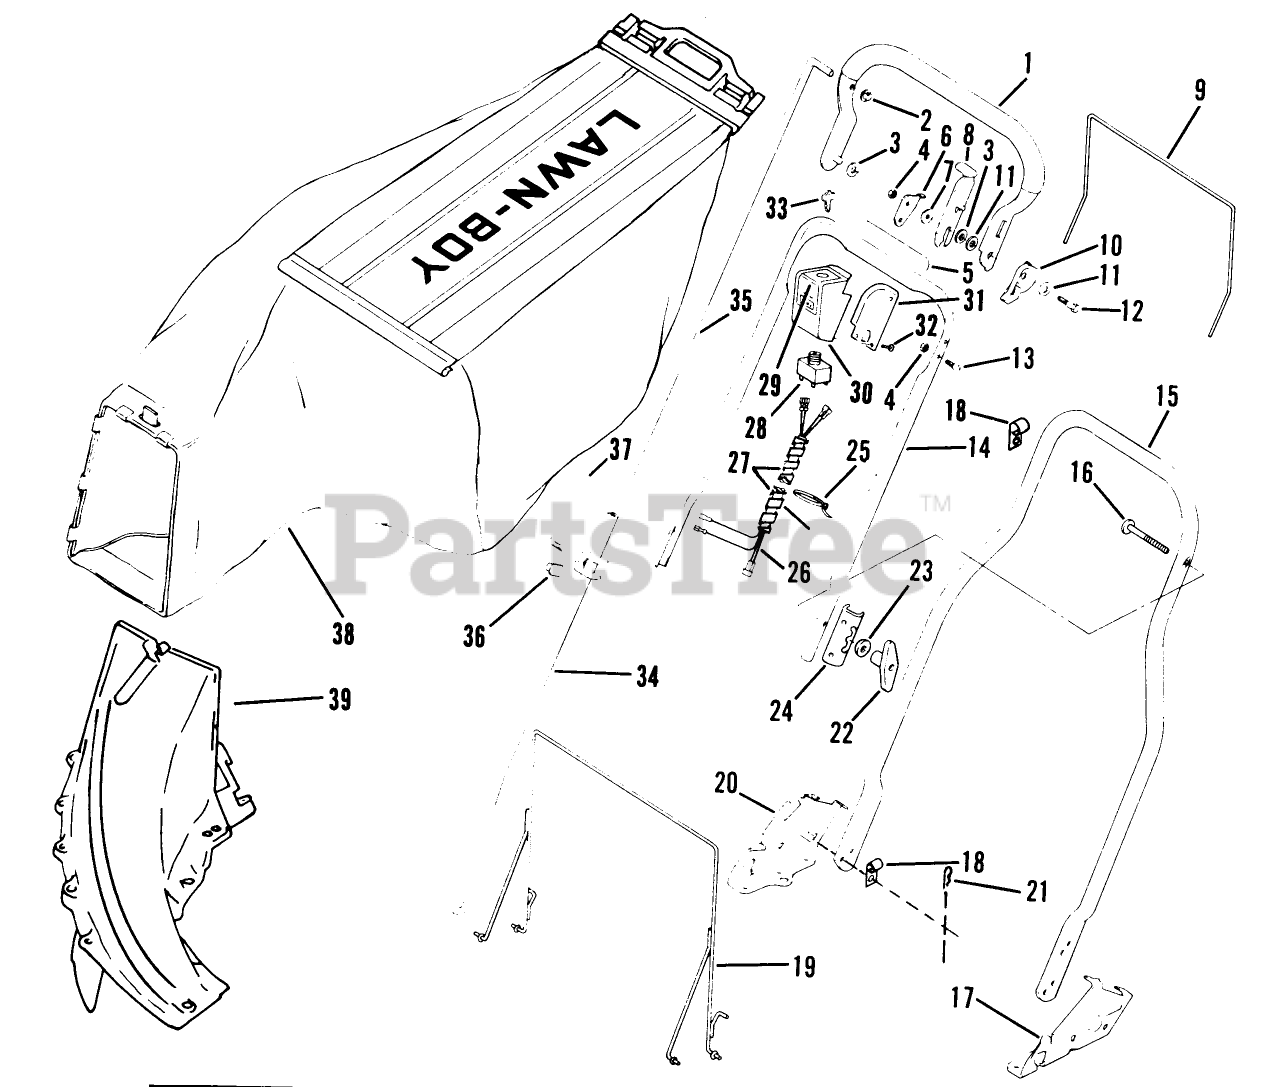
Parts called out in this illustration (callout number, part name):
3	WASHER M
4	LOCKNUT E
6	HANDLE STOP
7	WASHER
8	LEVER LOCKOUT
9	HANGER
12	BOLT PIONEER
13	SCREW-HANDLE STOP
14	HANDLE
20	HANDLE BRACKET
21	HAIR PIN
22	NUT-WING
23	WASHER-CURVED
24	BRACKET R/B 613462
30	HOUSING SWITCH
35	ROD CONTROL
